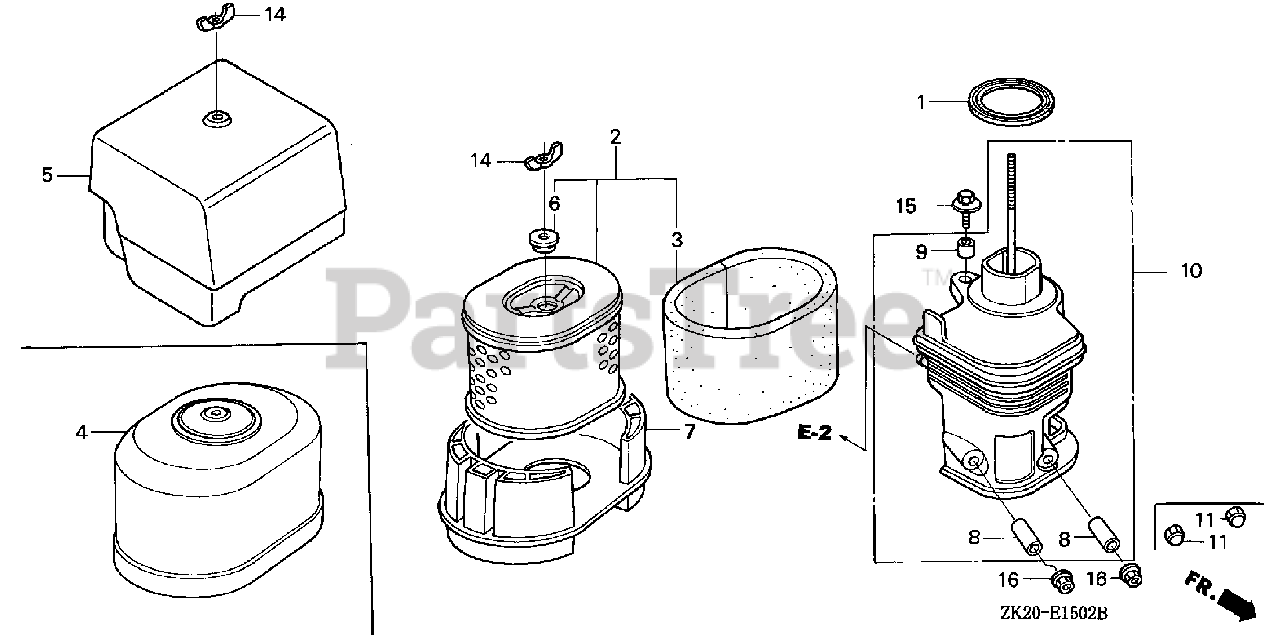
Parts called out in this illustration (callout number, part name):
1	GASKET, ELBOW
2	ELEMENT, AIR CLEANER (DUAL)
3	FILTER (OUTER)
5	COVER, AIR CLEANER
6	GROMMET, AIR CLEANER
7	NOSE, MUFFLER
8	COLLAR, AIR CLEANER
9	COLLAR B, AIR CLEANER
10	ELBOW, AIR CLEANER
14	WINGNUT, TOOL BOX SETTING
15	BOLT-WASHER (6X20)
16	NUT, FLANGE (6MM)
